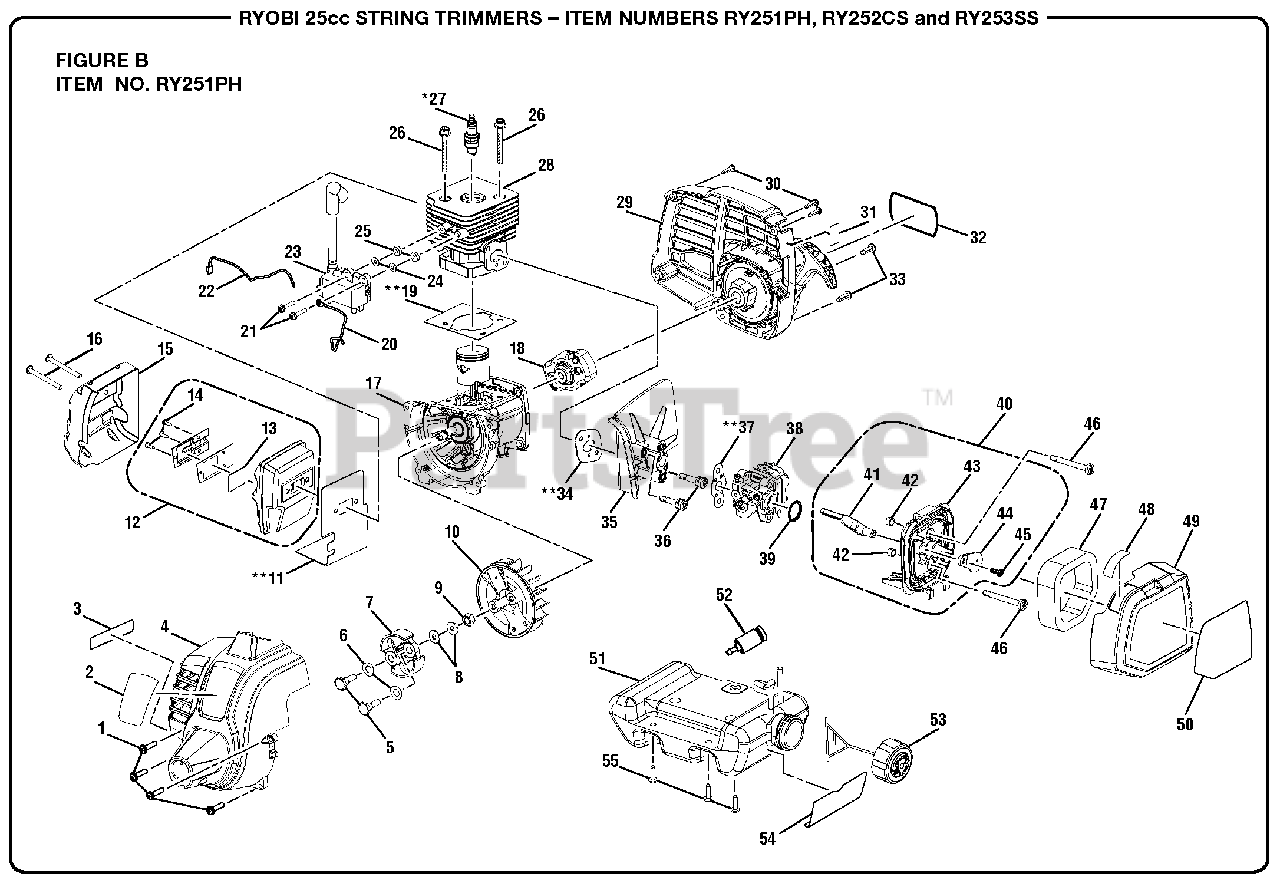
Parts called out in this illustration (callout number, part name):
1	Screw w/Washer (M5 x 20 mm, T20 Torx Pan Hd.)
2	Logo Label (Front)
3	Combustion Warning Label
4	Front Housing Assembly
5	Clutch Shoulder Bolt (M6 x 22.5 mm, Hex Hd.)
6	Curved Washer
7	Clutch Assembly
8	Washer (ID6 x OD15 x 1.2t)
9	Flywheel Nut
11	Muffler Gasket
12	Muffler Assembly
13	Screen
14	Screw (6-20 x 1/4 in., T20 Torx Pan Hd. S.T.)
15	Heat Shield
16	Screw (M5 x 50 mm, T25 Torx Pan Hd.)
17	Crankcase Assembly
18	Starter Cup
19	Gasket
20	Lead Wire (Red)
21	Screw w/Washer (M4 x 19 mm, T20 Torx Pan Hd. S.T.)
22	Lead Wire (Black)
23	Coil Boot Assembly
24	Washer (ID4.2 x OD10 x 1t)
25	Spacer (Phenolic)
26	Screw (M5 x 22 mm, Soc. Hd.)
27	Spark Plug (Champion RCJ4)
29	Rear Housing and Starter Assembly
30	Screw (M4 x 18 mm, T20 Torx Pan Hd. S.T.)
31	Primer Bulb Location Label
32	Logo Label (Rear)
33	Cap Screw w/Washer (M5 x 16 mm, T25 Torx Soc. Hd.)
34	Insulator Gasket
35	Heat Dam Insulator
36	Screw (M5 x 27 mm, T25 Torx Pan Hd. S.T.)
37	Gasket
38	Carburetor Assembly
39	Carburetor O-Ring
40	Airbox Base Assembly
41	Choke Lever
42	Compression Limiters
43	Air Box Base
44	Choke Plate
45	Screw (M4 x 12 mm, T20 Torx Pan Hd. S.T.)
46	Screw (M5 x 44 mm, T20 Torx Pan Hd.)
47	Air Filter
48	Choke Position Label
49	Airbox Cover
50	Starting Instructions Label
51	Fuel Tank and Cap Assembly
52	Fuel Filter
53	Fuel Cap Assembly
54	Fuel Mixture Label
55	Shoulder Screw (M4 x 14 mm, T25 Torx Truss Hd. S.T.)
